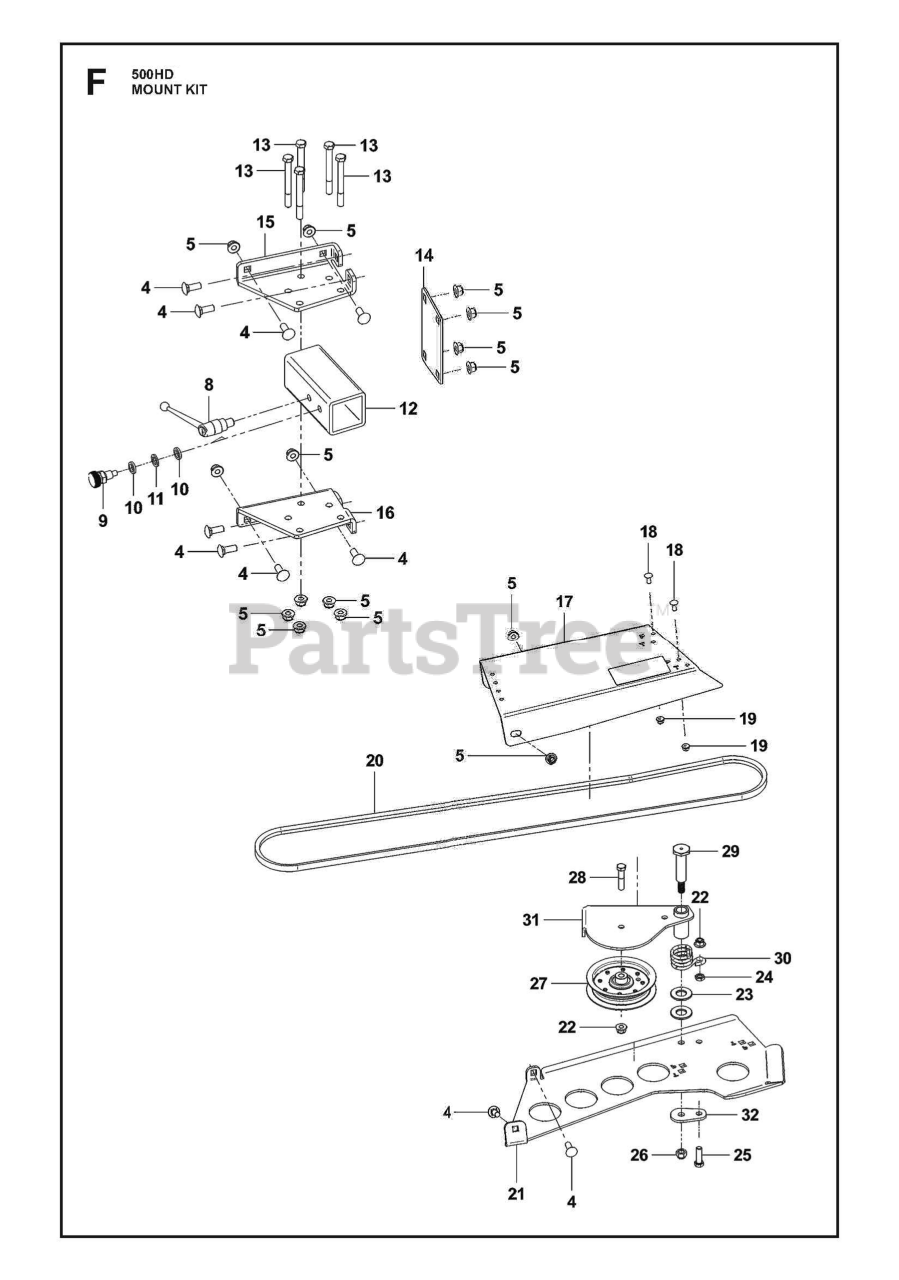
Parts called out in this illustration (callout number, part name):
4	Bolts
5	GSPW Nuts
8	HANDLES
9	PINS
10	WASHERS
11	BUSHING
12	ARMS
13	HCS 3/8-16 X 3-1/2 GR5 ZD
14	ARMS
15	ARMS
16	ARMS
17	COVERS
18	BOLT T
19	NUT FLG, NYLOCK, 1/4-20 GR G C
20	BELTS
21	PLATES
22	GSPW Nuts
23	WASHERS
24	Nuts
25	HCS 3/8-16 X 1-1/4 GR 8 ZD
26	NUT.LOCK.FLANGE.7/16
27	PULLEYS
28	BOLTS
29	BOLTS
30	SPRINGS
31	ARMS
32	PLATES
